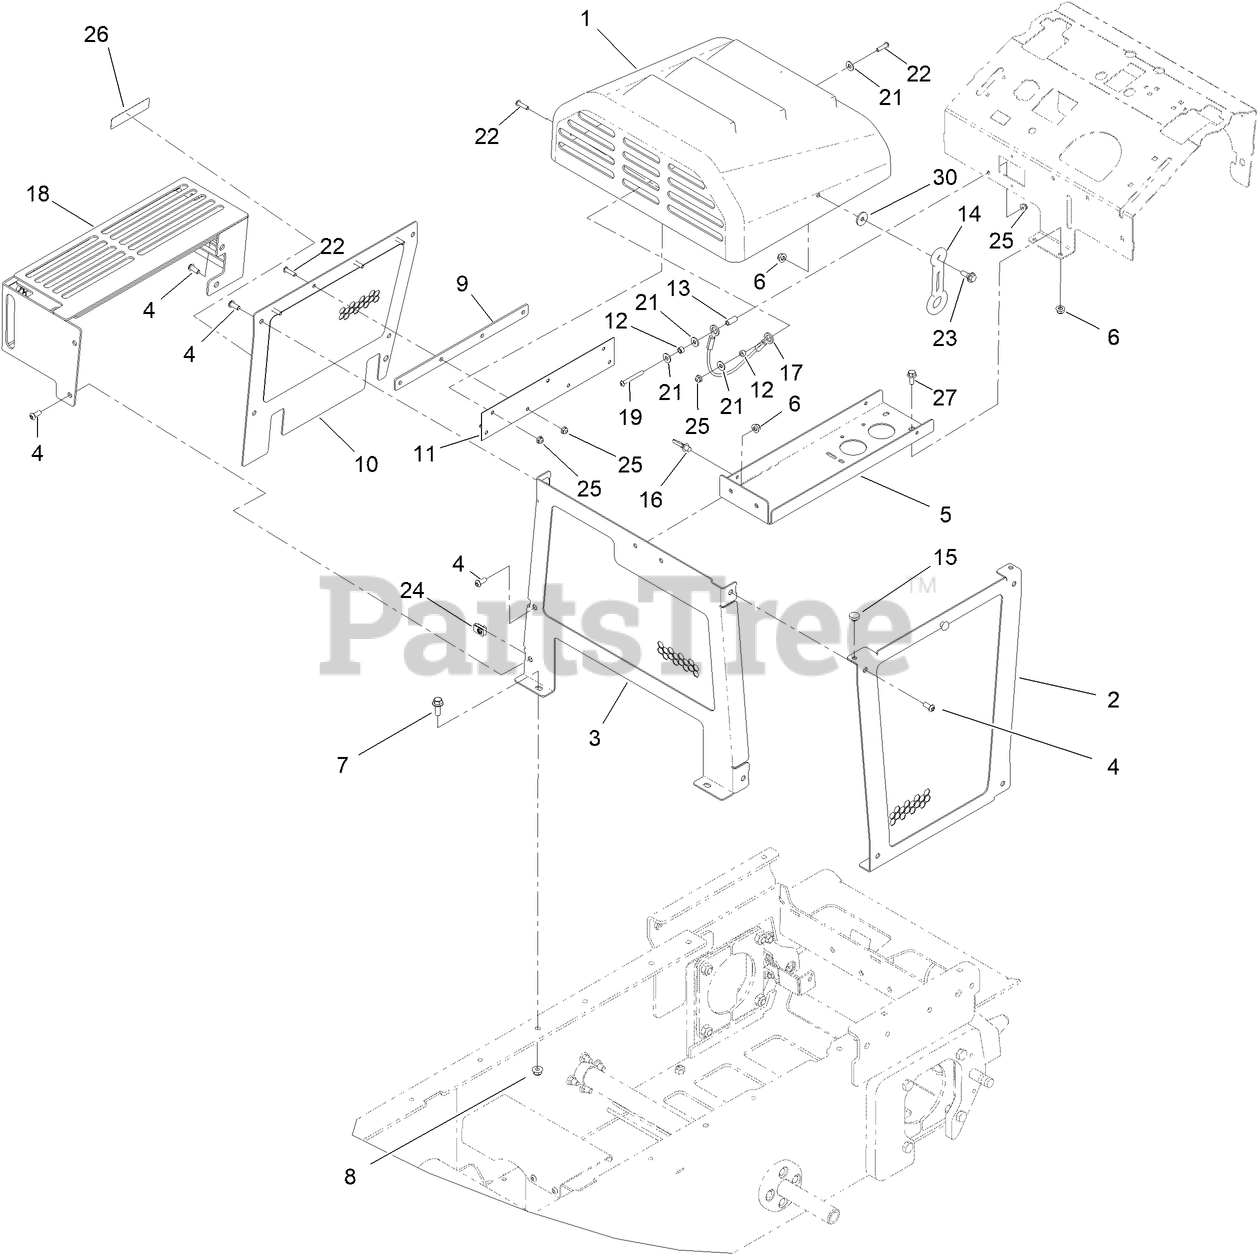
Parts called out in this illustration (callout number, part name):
2	PANEL-SIDE, LH
3	PANEL-FRONT
4	SCREW-HSBH
5	PLATFORM-BATTERY
6	NUT-HF, NI
7	SCREW-HHF
8	NUT-HF, NI
9	PLATE-SPACER, HOOD
10	PANEL-SIDE, UPPER
11	HINGE-HOOD
12	SPACER-BLADE, ROTOR
13	SPACER-BRAKE, PARKING
14	LATCH-RUBBER
15	BUMPER
16	CLIP-TIE
17	LANYARD
18	GUARD-MUFFLER
19	SCREW-HSBH
21	WASHER-FLAT
22	SCREW-HSBH
23	SCREW-SHOULDER
24	NUT-CLIP, U
25	NUT-HF
26	DECAL-ARRESTOR, SPARK
27	SCREW-HHF
30	WASHER-FLAT
